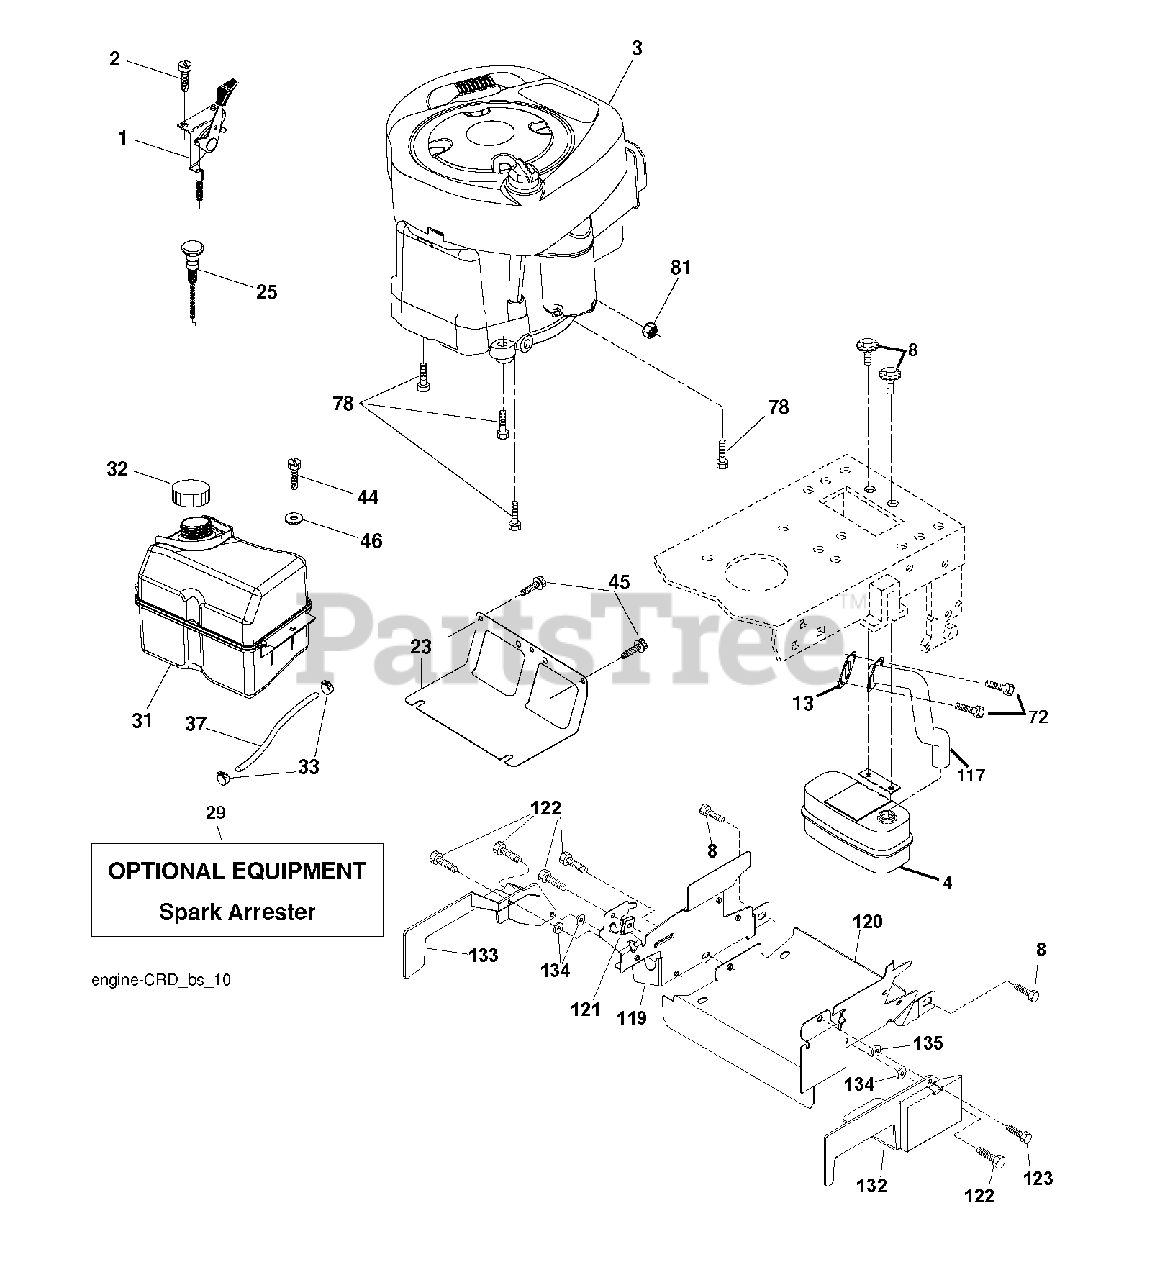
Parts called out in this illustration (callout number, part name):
1	CONTROL TH/CH FLAG
2	SCREW
4	MUFFLER.SINGLE.CYL.KOHL/B&S
8	BOLT, 5/16-18 X 1 3/4
13	REPL BY 532 27 22-93
23	SHEILD.BROWNING.DBR.GUARD
29	ARRESTER SPARK (OPTIONAL)
32	FUEL CAP
33	HOSE CLAMP
37	LINE.FUEL.20
44	SCREW HEXWSHR 1/4-20X3/4
45	SCREW, 3/8-16X3/4
72	SCREW.SOCKET HD.5/16-1
78	SCREW.3/8-16
81	NUT
117	EXHAUST.TUBE.B&S.
122	SCREW.1/4-20X5/8
123	SCREW, 5/16-18 X 1/2
134	PALNUT 1/4
